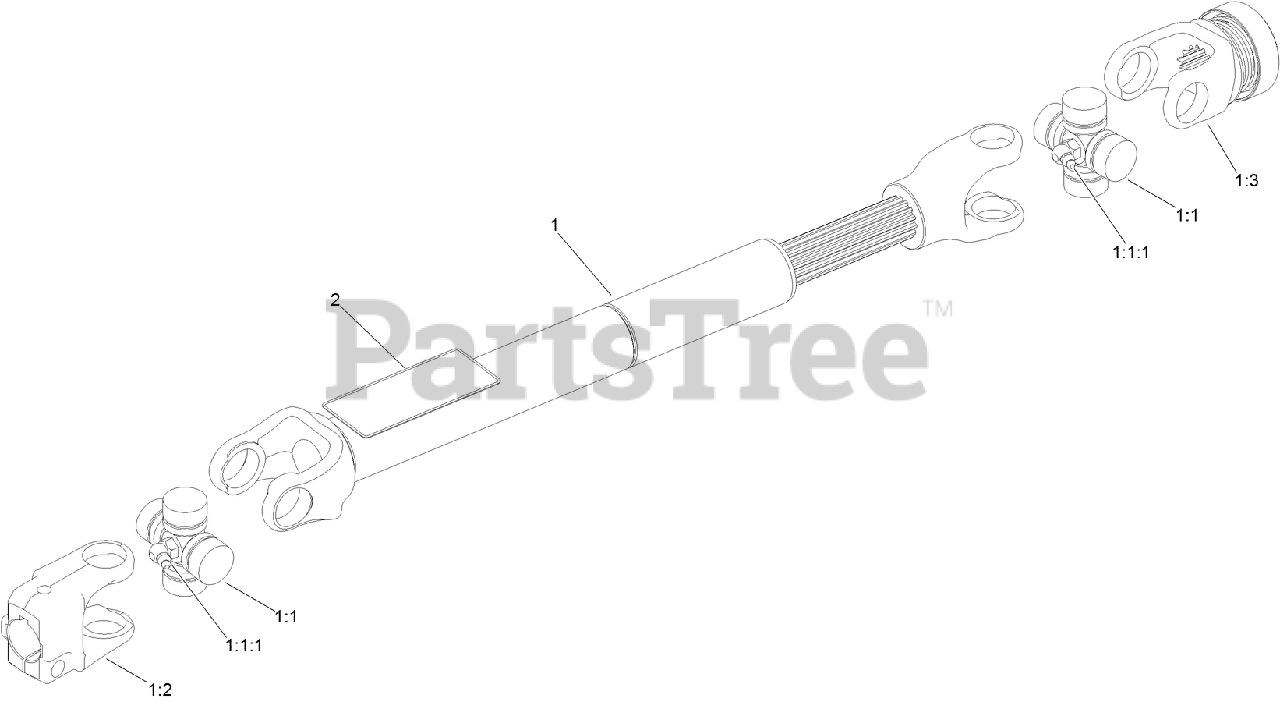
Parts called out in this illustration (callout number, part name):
1	DRIVE SHAFT-TELESCOPING
1:1	U-JOINT KIT
1:1:1	FITTING-GREASE
1:2	YOKE-KEYED
1:3	YOKE-QUICK DISCONNECT
2	DECAL-DRIVELINE
